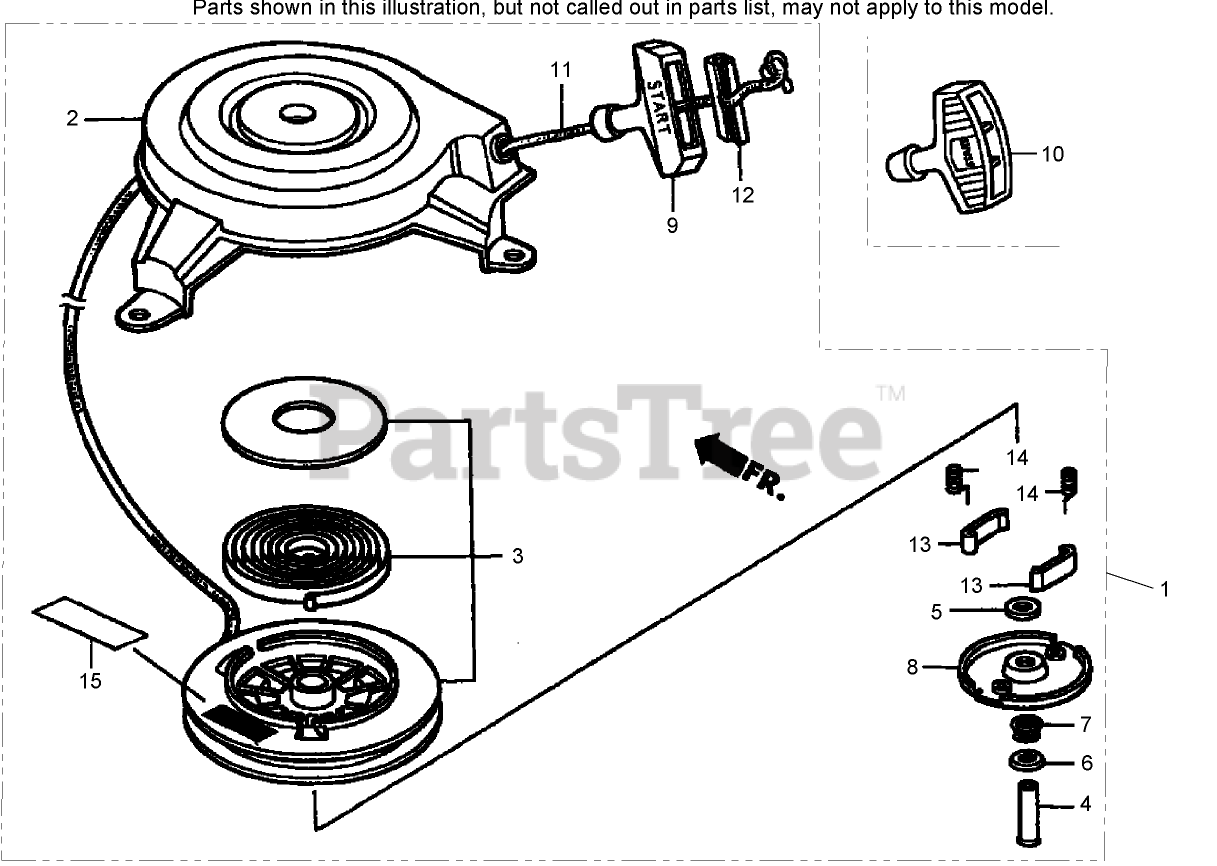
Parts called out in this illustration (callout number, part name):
1	RECOIL STARTER ASM
2	HOUSING ASM
3	PULLEY AND SPRING ASM
4	Pin-Center
5	Plate A-Friction
6	PLATE B-FRICTION
7	Spring-Friction
8	Retainer
9	Handle
11	ROPE-STARTER, RECOIL
12	Handle-Reinforcement
13	Ratchet-Starter
14	Spring-Dog
